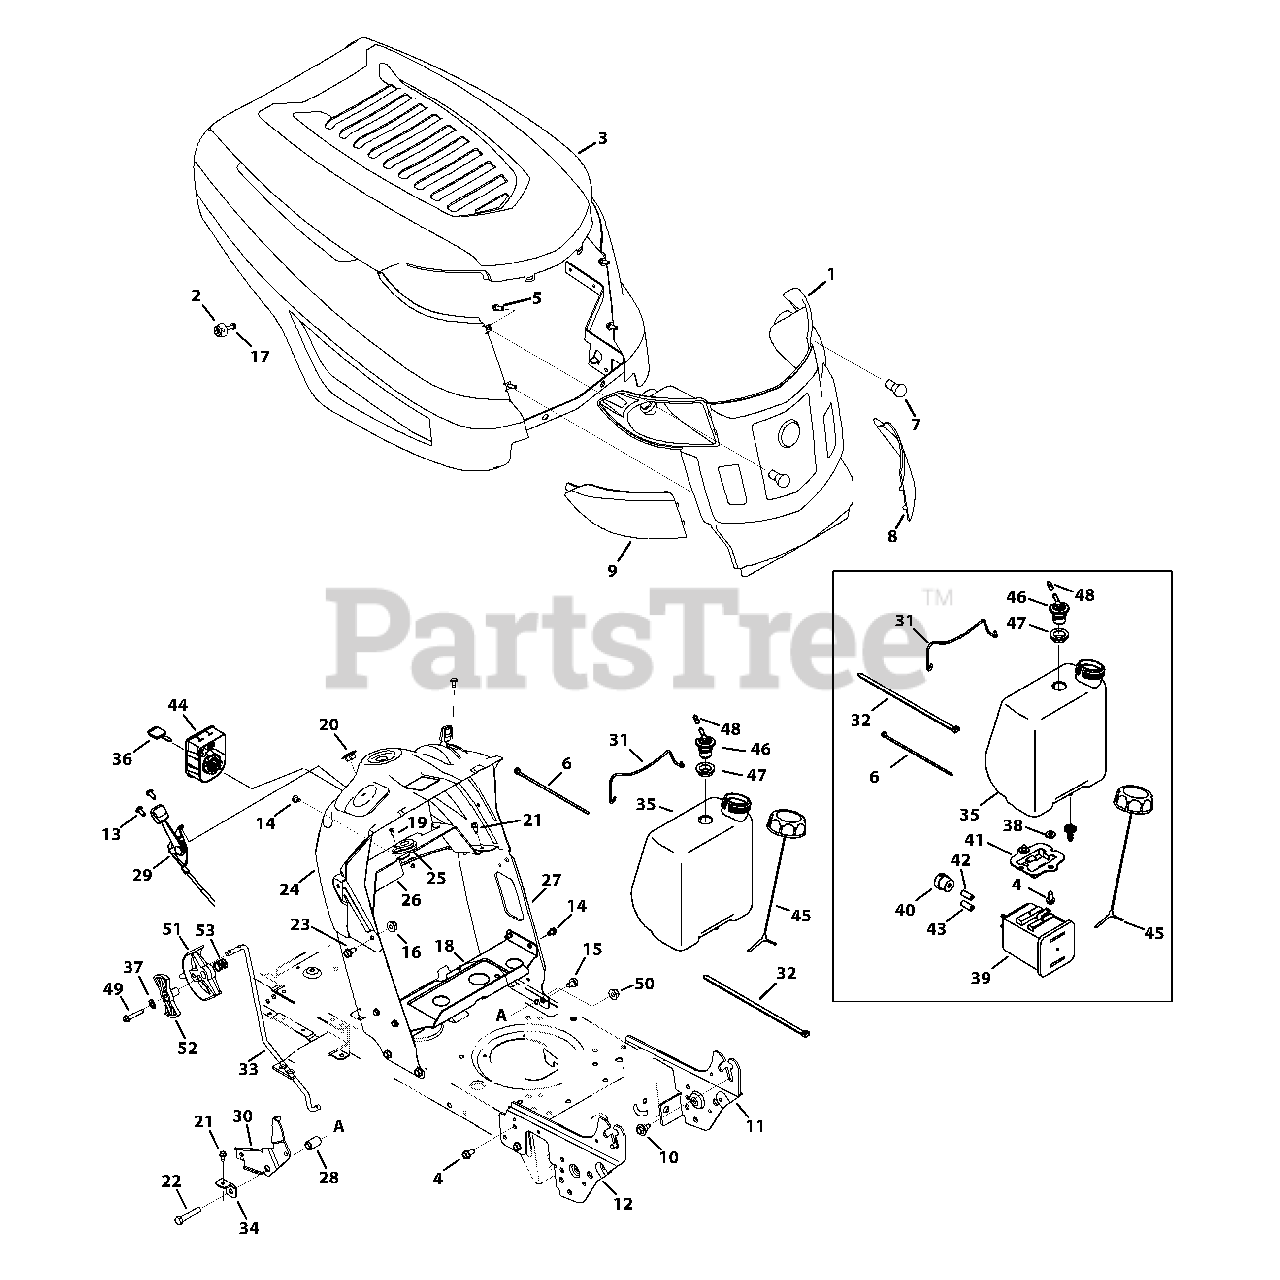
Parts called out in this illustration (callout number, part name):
1	Grill Assembly, Troy-Bilt
2	K-Style Bumper
4	Screw, 5/16-18 x .750
5	Screw, 1/4-15 x .750
6	Cable Tie
9	Right Lens
10	Shoulder Screw, 5/16-18 x .43 x .29
11	Left Support Pivot Bracket
12	Right Support Pivot Bracket
13	Screw, 1/4-20 x .500
14	Screw, 1/4-20 x .500
15	Screw, 5/16-18 x .625
16	Flangelock Nut, 5/16-18
17	Screw, #12-16 x 1.25
18	Gas Tank Support Bracket
19	Screw, #10-16 x .500
20	Choke Plug
21	Tap Screw, 1/4-20, 0.625
22	Hex Screw, 3/8-16 x 2.0
23	Hex Screw, 5/16-18 x .625
24	Dash, Upper
25	Bearing, .628 ID x 1.36
26	Bracket, Steering Support
27	Dash, Lower
28	Flange Spacer, .390 x .671 x 1.095
29	Throttle/Choke Cable
30	Speed Latch - No RMC
31	Battery Assembly Rod
32	Cable Tie
33	Speed Control Rod
34	Speed Latch Tab
35	1.36 Gallon Fuel Tank
36	Key, Assembly
37	Lock Washer, 1/4
38	Flat Washer, .344 x .750 x .120
39	5 Gallon Carbon Canister
40	Vent Filter Canister
41	Canister Adapter Bracket
42	Fuel Hose, White
43	Fuel Hose, Yellow
44	3 Position Key Switch
45	Fuel Cap, 2.25"
45	Fuel Cap, 2.25" EPA
46	Rollover Valve
47	Rubber Grommet, 23 x 3.55
48	Hose Vent, 3/16 EPA
49	Hex Washer Screw, 1/4-20 x 1.50
50	Flangelock Nut, 3/8-16
51	Shift Lever
52	Index Control
53	Compr. Spring, .72 OD x .78
